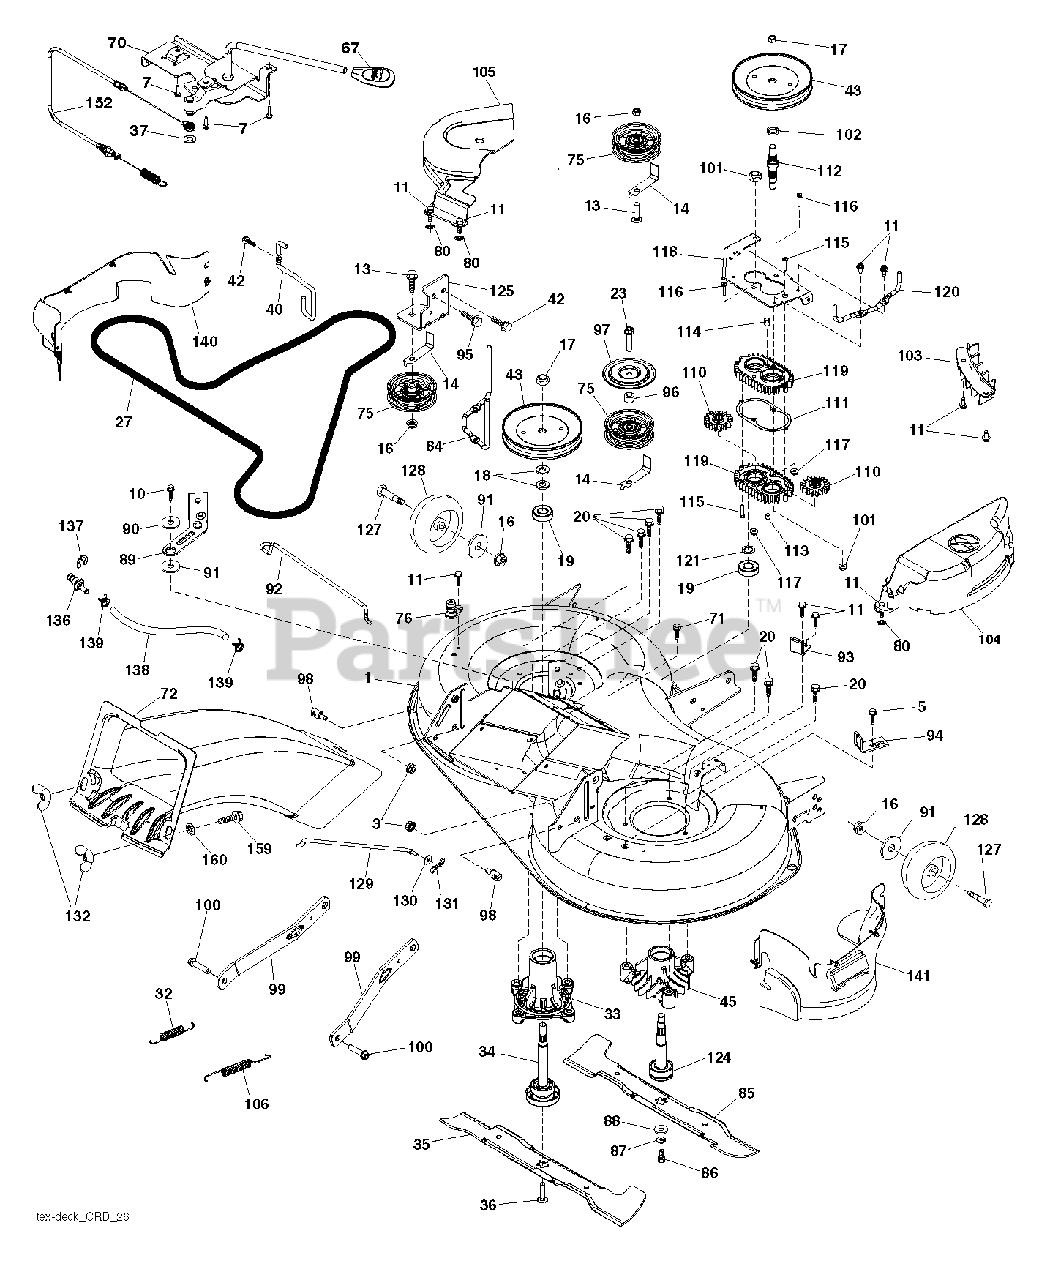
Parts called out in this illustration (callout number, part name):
3	NUT LOCK HEX FLANGE 5/16-18
5	BOLT.5/16HEX.WHS.HD
7	SCREW.#10 X 0.750.BOS THREAD
10	SCREW 3/8-16X1
11	SCREW.1/4-20X5/8
13	BOLT.3/8-16X1.50
14	KEEPER, BELT IDLER
16	NUT LOCK FLG 3/8-16 UNC
17	NUT.FLANGE.LOCK.TOP
18	WASHER.SPACER.MANDREL
20	SCREW, WASHER HEAD
23	SCREW LT
32	SPRING RETURN
33	HOUSING MANDREL
34	SHAFT.ASM.MDRL.N/GREASE.38
35	BLADE.3N1.LH.CRD.97
36	BOLT.WASHER.ASM.7/16-2
40	KEEPER BELT ENGINE LH
42	SCREW
43	PULLEY.MANDREL.5.438.PD
45	HOUSING.MANDREL
67	HANDLE.CLUTCH.CABLE.LT
70	CLUTCH.ASM.MANUAL.LT.PRED
71	SCREW 3/8-16X1/2
75	FLAT IDLER PULLEY
80	PALNUT 1/4
84	KEEPER.BELT.LH.MANDREL
85	BLADE.3N1.LH.CRD.97
87	LOCKWASHER
88	WASHER.BLADE
90	SPACER.RETAINER
94	BRKT.CLUTCH.CABLE
95	SCREW, 3/8-16X3/4
98	STUD.FASTNER.W/ANTI-ROTATE
99	ARM.SUSPENSION.MOWER.R
100	BOLT.SHOULDER
102	SPACER BEARING
106	SPRING.BRAKE.RETURN.38"
117	NUT T
127	BOLT.SHOULDER.3/8-16X3-5/8
128	WHEEL. GUAGE RALLY
129	ROD.ANTI.SWAY.48/54"K4
130	WASHER
131	PIN.COTTER.5/16.BOW TI
132	KNOB.HANDLE.3/8.TRI-POINT.BLAC
137	RING CLIP
159	BOLT
